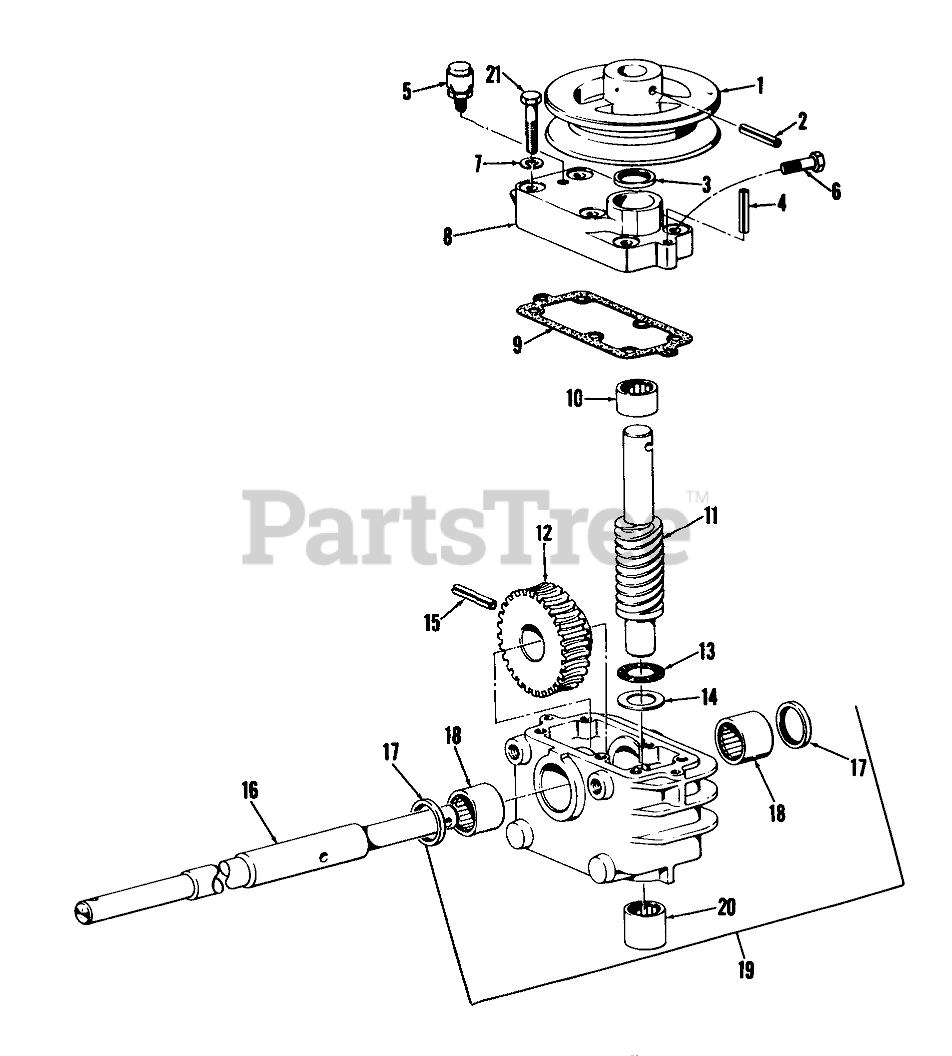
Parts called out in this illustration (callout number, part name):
1	Pulley
2	PIN-ROLL, SLOTTED
3	5/8 X .125 OIL SEAL
4	PIN-ROLL, SLOTTED
6	SCREW-HH
7	WASHER-LOCK
8	Cover, Gear Case
9	Gasket
10	.625 NEEDLE BEARING
11	Shaft, Worm
12	WORM GEAR
13	NEEDLE BRG
14	BEARING-THRUST
15	PIN-ROLL
16	Drive Shaft
17	SEAL-OIL
18	BEARING-NEEDLE
19	Gear Case Assy. w/Bearing (Incl. Ref. #17, 18 & 20)
20	.625 NEEDLE BEARING
21	SCREW-HH
